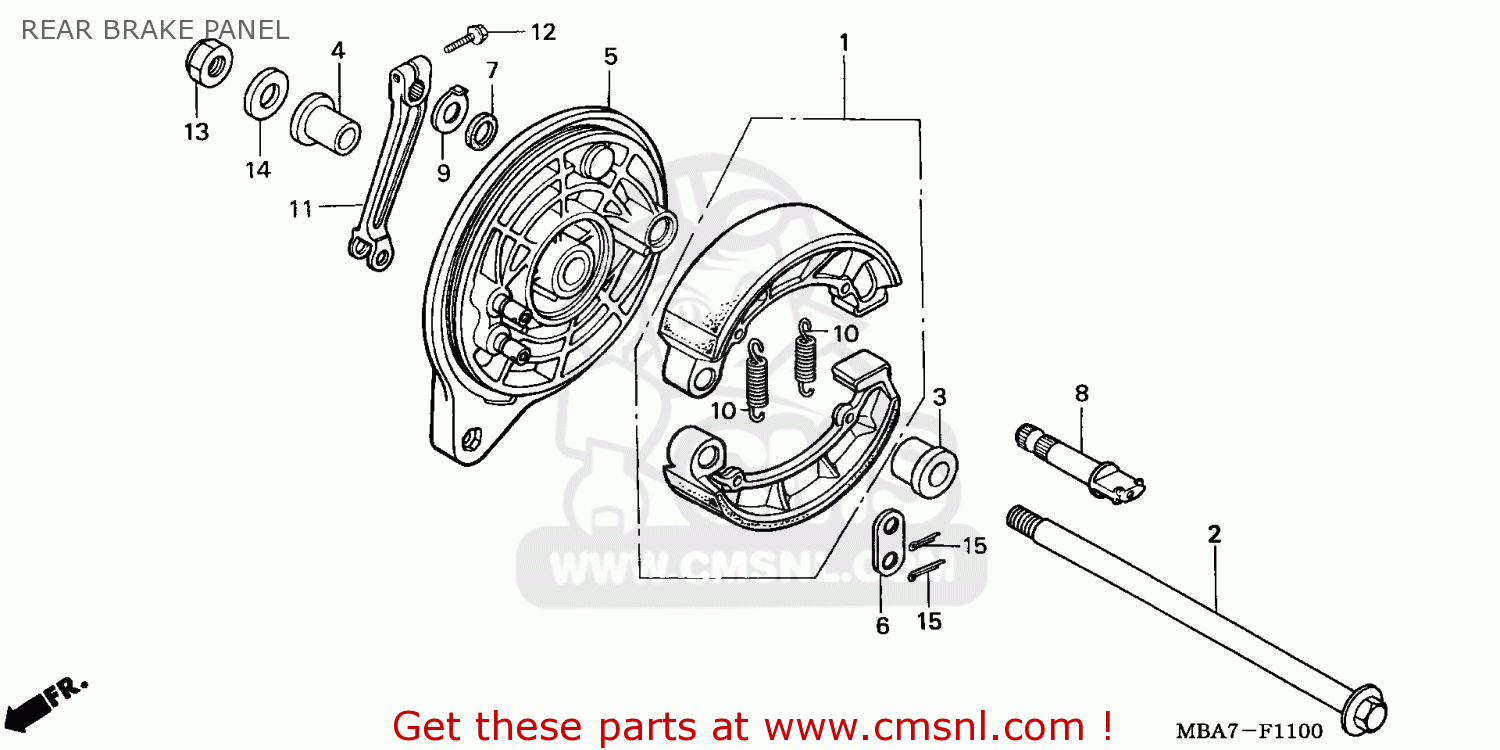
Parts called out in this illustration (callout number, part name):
1	SHOE SET,BRAKE (NAS)
2	AXLE,RR WHEEL
3	COLLAR,REAR WHEEL
4	COLLAR,WHEEL SIDE
5	PANEL COMP.,REAR
6	WASHER,ANCHER PIN
7	SEAL BRAKE CAM
8	CAM,REAR BRAKE
9	INDICATOR,RR.BRK.
10	SPRING,RR.BRAKE
11	ARM,REAR BRAKE
12	BOLT,FLANGE,8X25
13	NUT,U,18MM
14	WASHER,18X32X2
15	PIN COTTER 2.5MM
